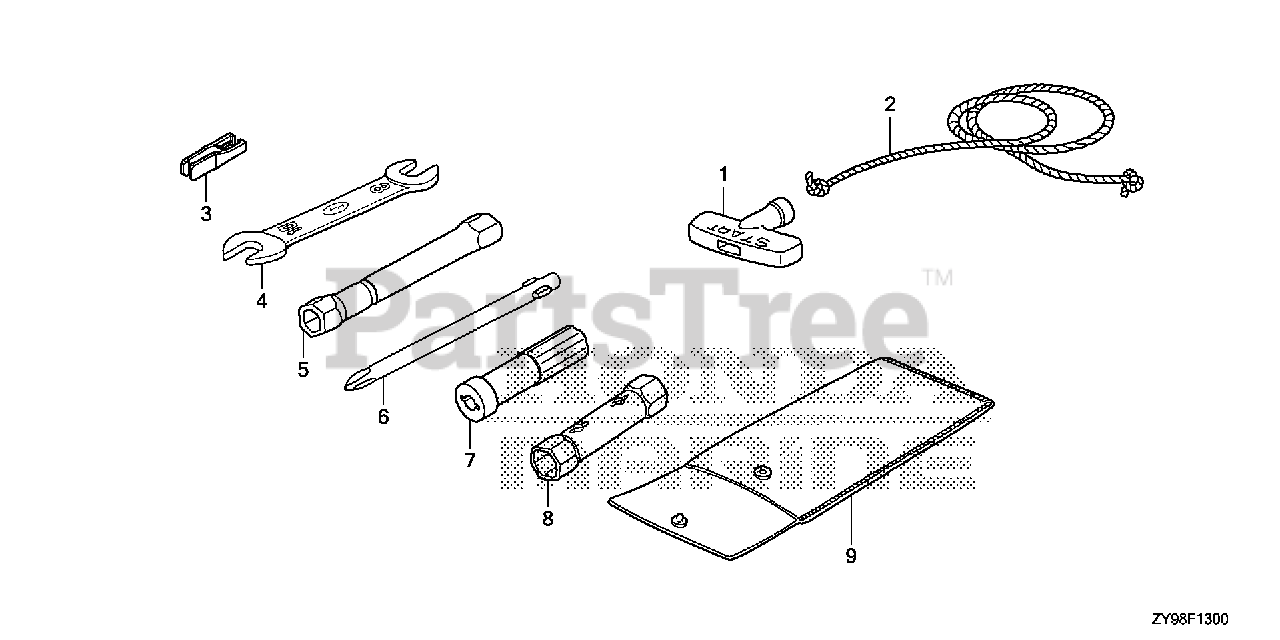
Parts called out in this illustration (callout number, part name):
1	KNOB, RECOIL SRARTER
2	ROPE, RECOIL STARTER (1300MM)
3	PULLER, MINI FUSE (SUMITOMO)
4	SPANNER (8X10)
5	WRENCH, PLUG
6	DRIVER 1, PLUS SCREW (NO.2)
7	GRIP, SCREW DRIVER
8	WRENCH, BOX (P18X19)
